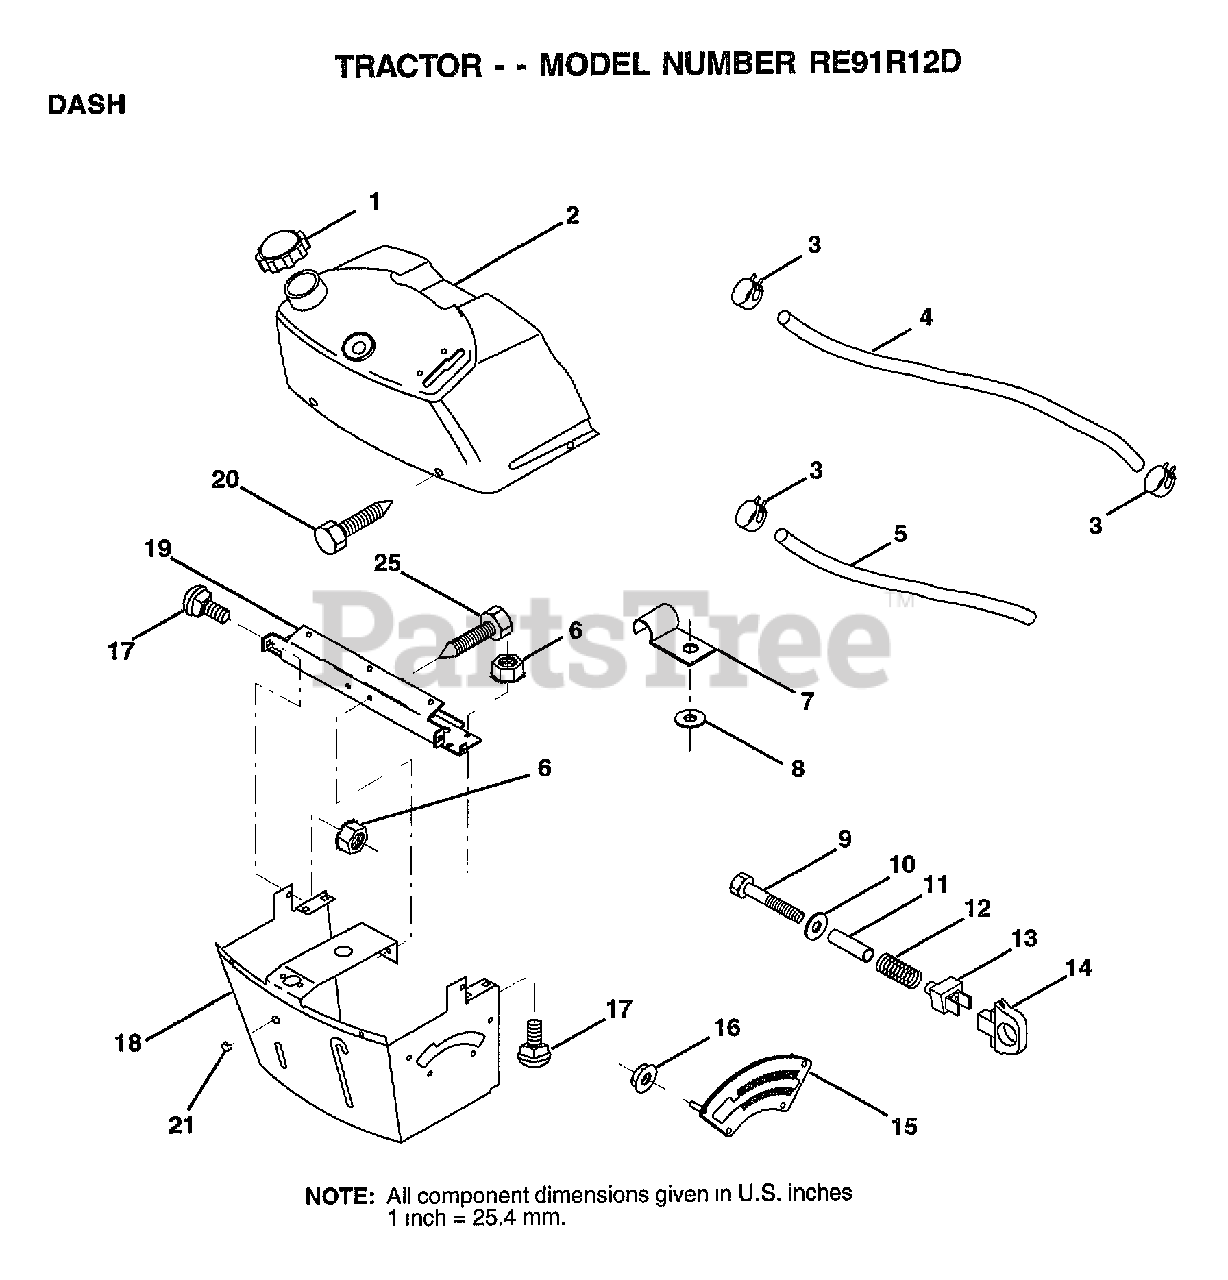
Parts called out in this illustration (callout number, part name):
1	CAP BLK FUEL LR
2	TANK.ASM.DASH.LR
3	HOSE CLAMP
5	FUEL LINE T
6	NUT HXKEP 1/4X20
7	CLIP T
8	WASHER PM
9	BOLT
11	SPACER SPLIT
13	SPRING M
13	"KNOB,HGT RETAINER"
14	KNOB
15	ADJUSTER QUAD
16	NUT
17	BOLT
18	SUPT ASSY DASH
19	CROSS BRACE
20	SCREW.1/4-20X1/2
21	PLUG DOME
25	SCREW LT
